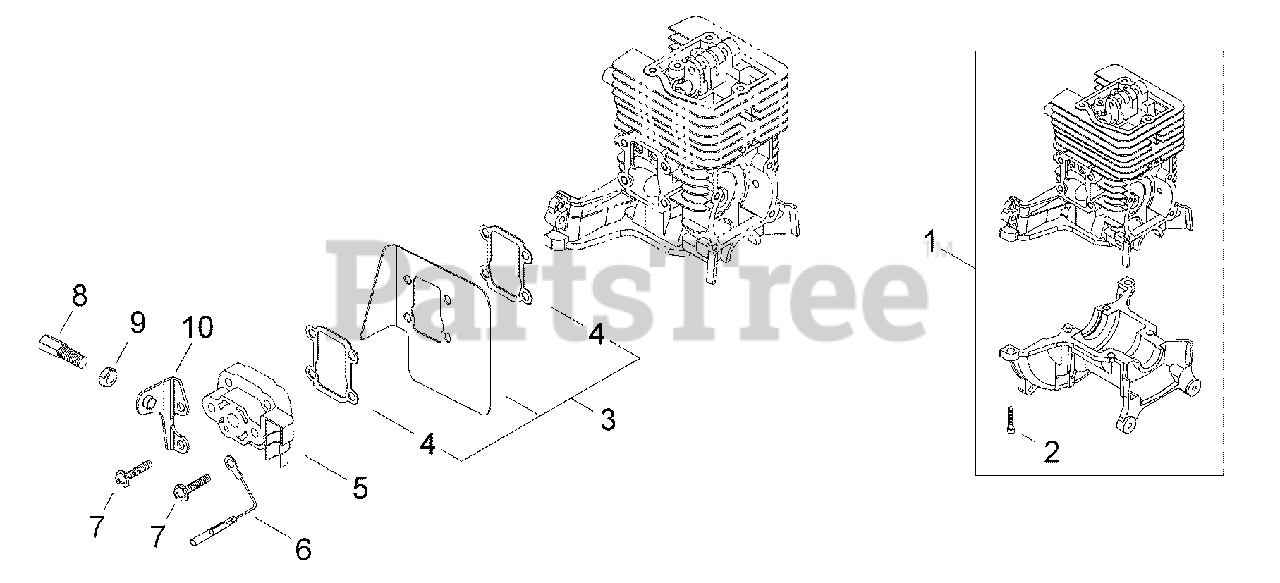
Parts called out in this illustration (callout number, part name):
1	CYLINDER BLOCK SET
2	SCREW - 5X16
3	INTAKE SHIELD KIT
4	SHIELD, INTAKE
5	INSULATOR
6	LEAD - GROUND
7	SCREW - 5X22
8	NUT, CABLE ADJUST
9	LOCKNUT - 6
10	BRACKET, THROTTLE CABLE
